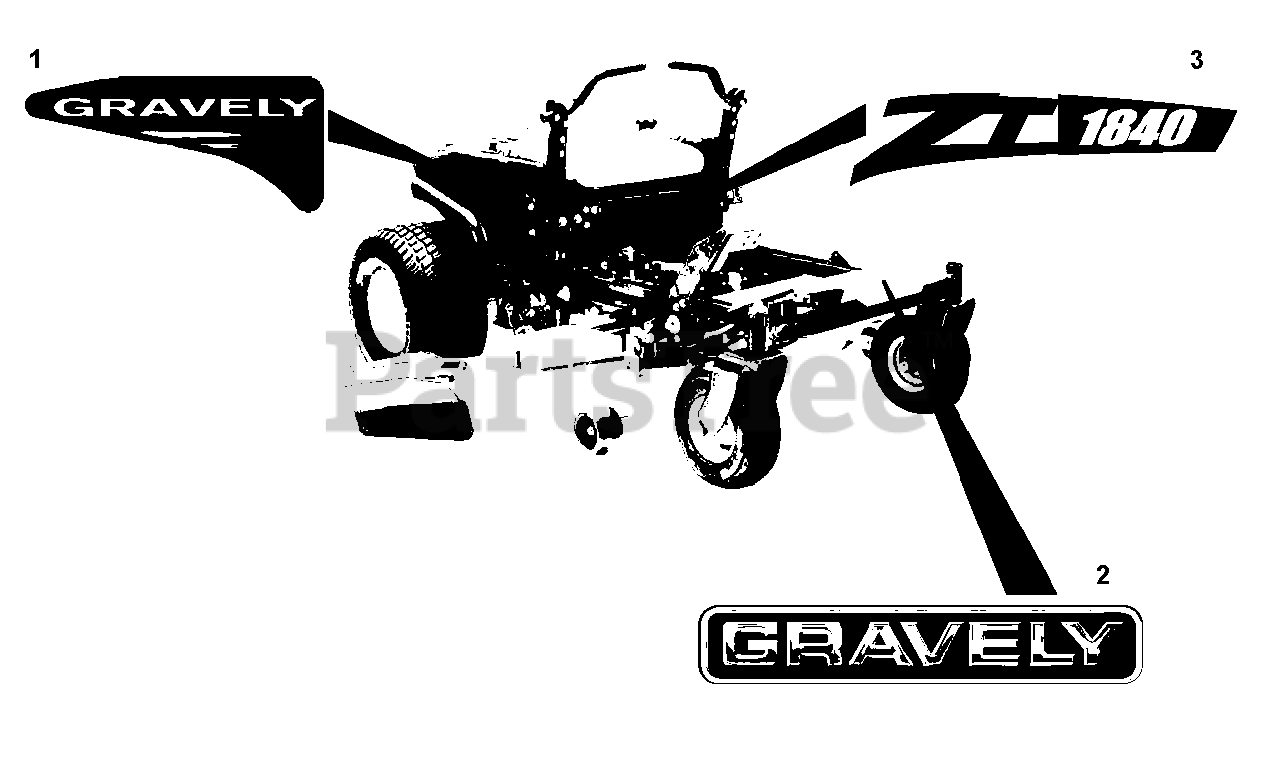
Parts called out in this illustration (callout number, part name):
1	Decal, Gravely ZT RH Fender
2	Decal, Gravely Logo
3	Decal, Gravely 1634 ZT
